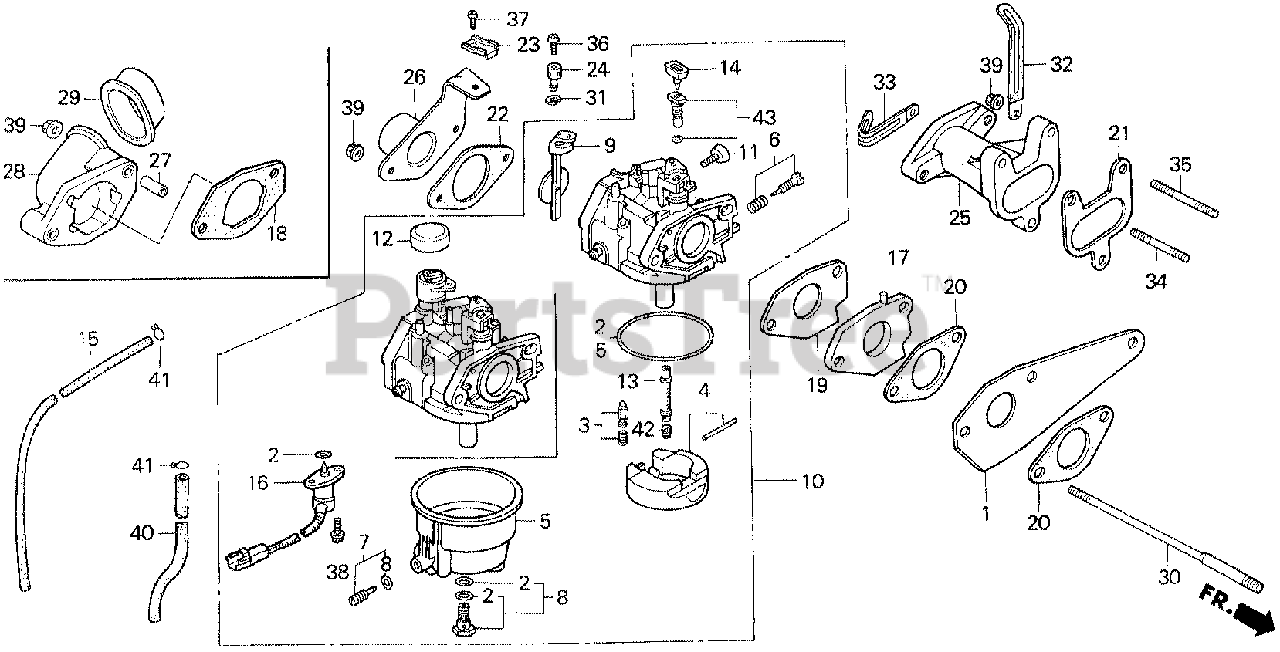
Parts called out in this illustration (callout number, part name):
1	STAY, TIMING BELT
2	GASKET SET
3	VALVE SET, FLOAT
4	FLOAT SET
5	CHAMBER SET, FLOAT
6	SCREW SET
7	SCREW SET, DRAIN
8	SCREW SET B
9	CHOKE SET
10	CARBURETOR ASSY. (BE77B D)
11	SCREW, THROTTLE STOP
13	NOZZLE, MAIN
14	COLLAR, SET
15	TUBE, AIR VENT
16	VALVE ASSY., SOLENOID
17	INSULATOR, CARBURETOR
19	GASKET, CARBURETOR
20	GASKET, INSULATOR
21	GASKET, IN. MANIFOLD
22	GASKET, AIR CLEANER
23	HOLDER, CONTROL CABLE
24	HOLDER, CABLE
25	MANIFOLD, IN.
26	PIPE, AIR IN.
30	BOLT, STUD (8X100)
31	CIRCLIP (5MM)
33	CLIP (2X60)
34	BOLT, STUD (6X32)
35	BOLT, STUD (6X28)
36	SCREW, PAN (4X8)
37	SCREW, PAN (5X10)
38	SCREW-WASHER (5X12)
39	NUT, FLANGE (6MM)
40	BULK HOSE, FUEL (4.5X3000) (Honda Code 5137104). (4.5X300)
41	CLIP, TUBE (B8)
42	JET, MAIN (#88)
42	JET, MAIN (#90)
42	JET, MAIN (#92)
43	JET SET, PILOT (#40)
